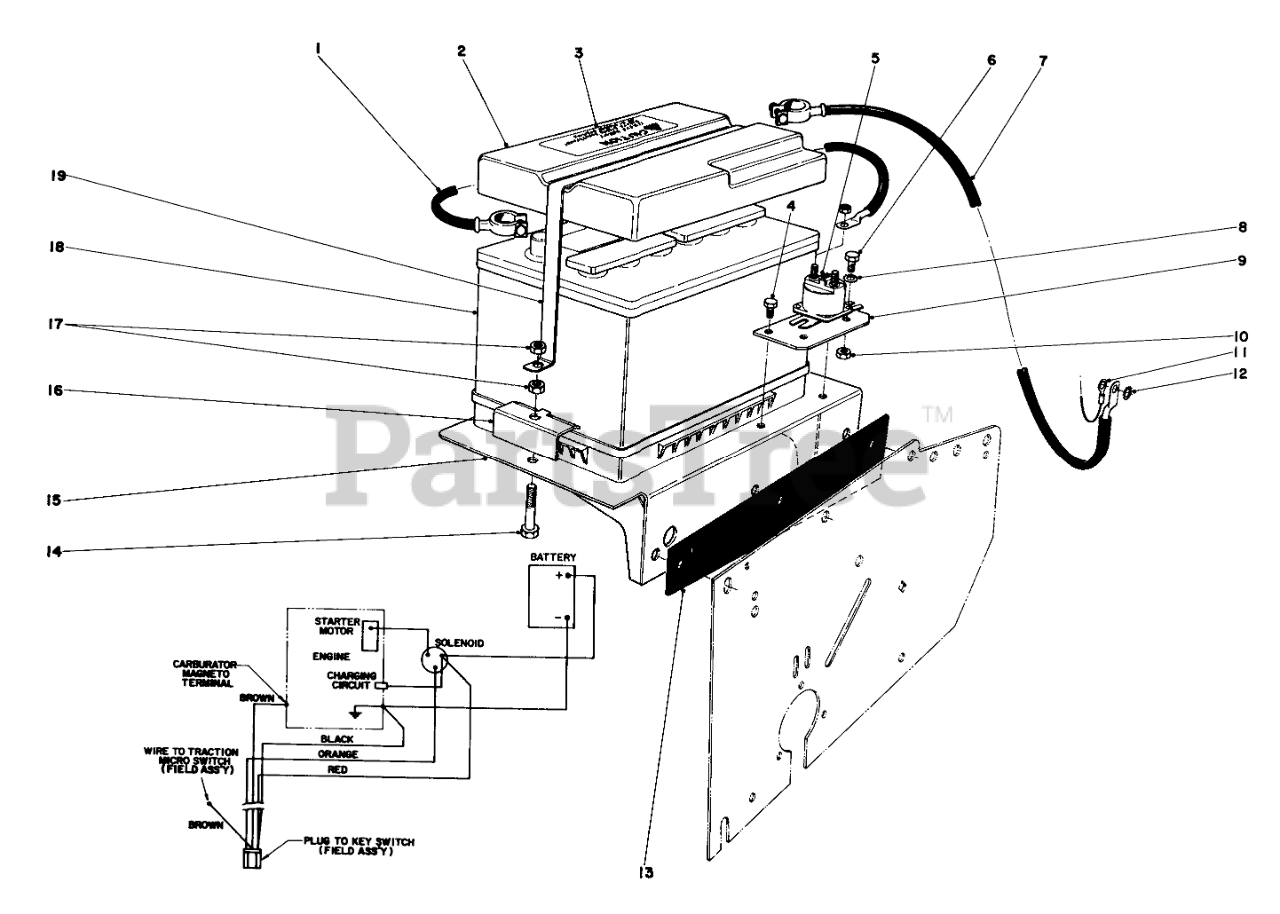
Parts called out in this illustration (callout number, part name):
1	BATT-SOLENOID CABLE
2	Cover-Battery (Incl. Ref. #3)
3	Decal
4	SCREW-HWH
5	SOLENOID
6	SCREW-HH
7	BATT-GROUND CABLE
8	WASHER-LOCK/EXT
9	Bracket Solenoid
10	NUT-LOCK, NI
11	Ignition Wire Harness
12	WASHER-LOCK
13	Batery Isolation Pad
14	SCREW-HH
15	Battery Mounting Plate
16	BATTERY CLAMP
17	NUT-HEX
18	Battery
19	Strap Battery
